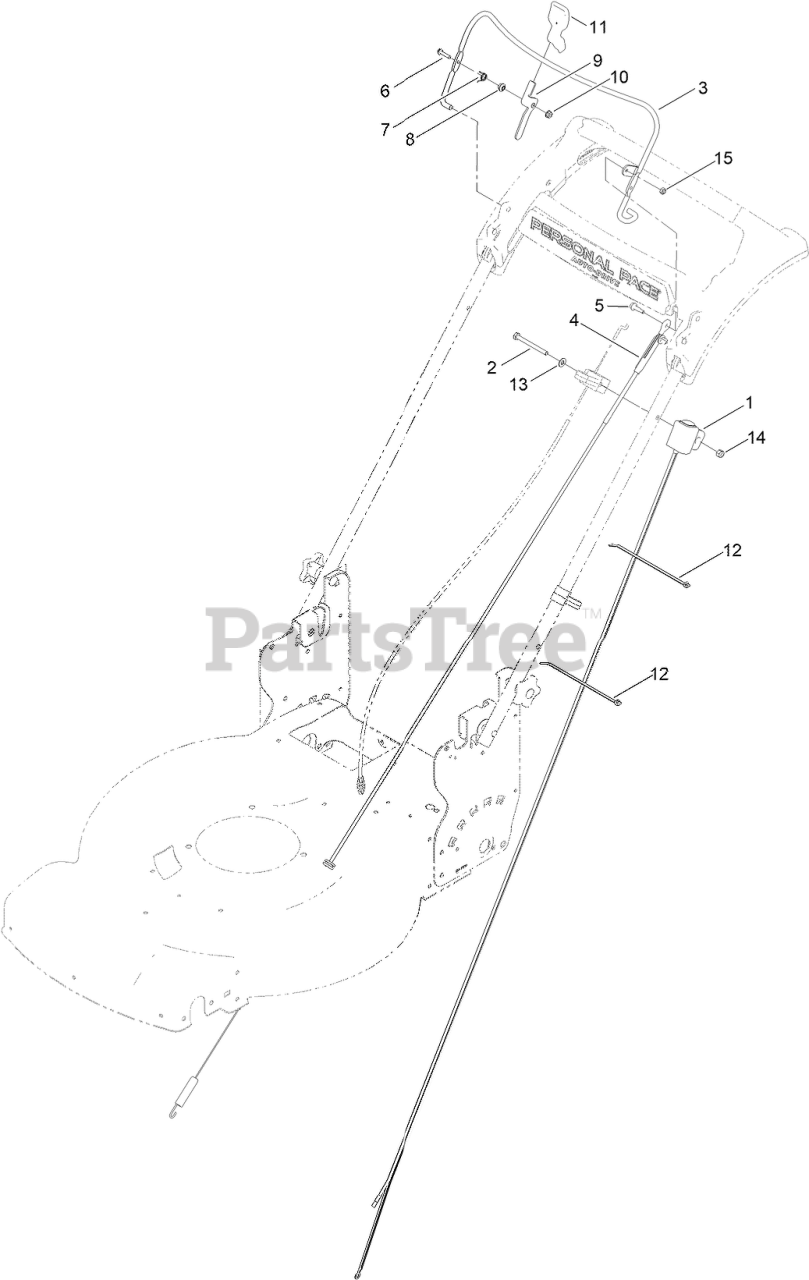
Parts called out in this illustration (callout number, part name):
1	SWITCH HOUSING ASM
2	SCREW-HH
3	BAIL-BRAKE [BLACK]
4	CABLE-BRAKE
5	SCREW-SHOULDER
6	SCREW-HWH
7	SPRING-TORSION
8	SPACER
10	NUT-HEX FLANGE
12	TIE-CABLE
13	WASHER-FLAT
14	NUT-HEX
15	NUT-HEX
